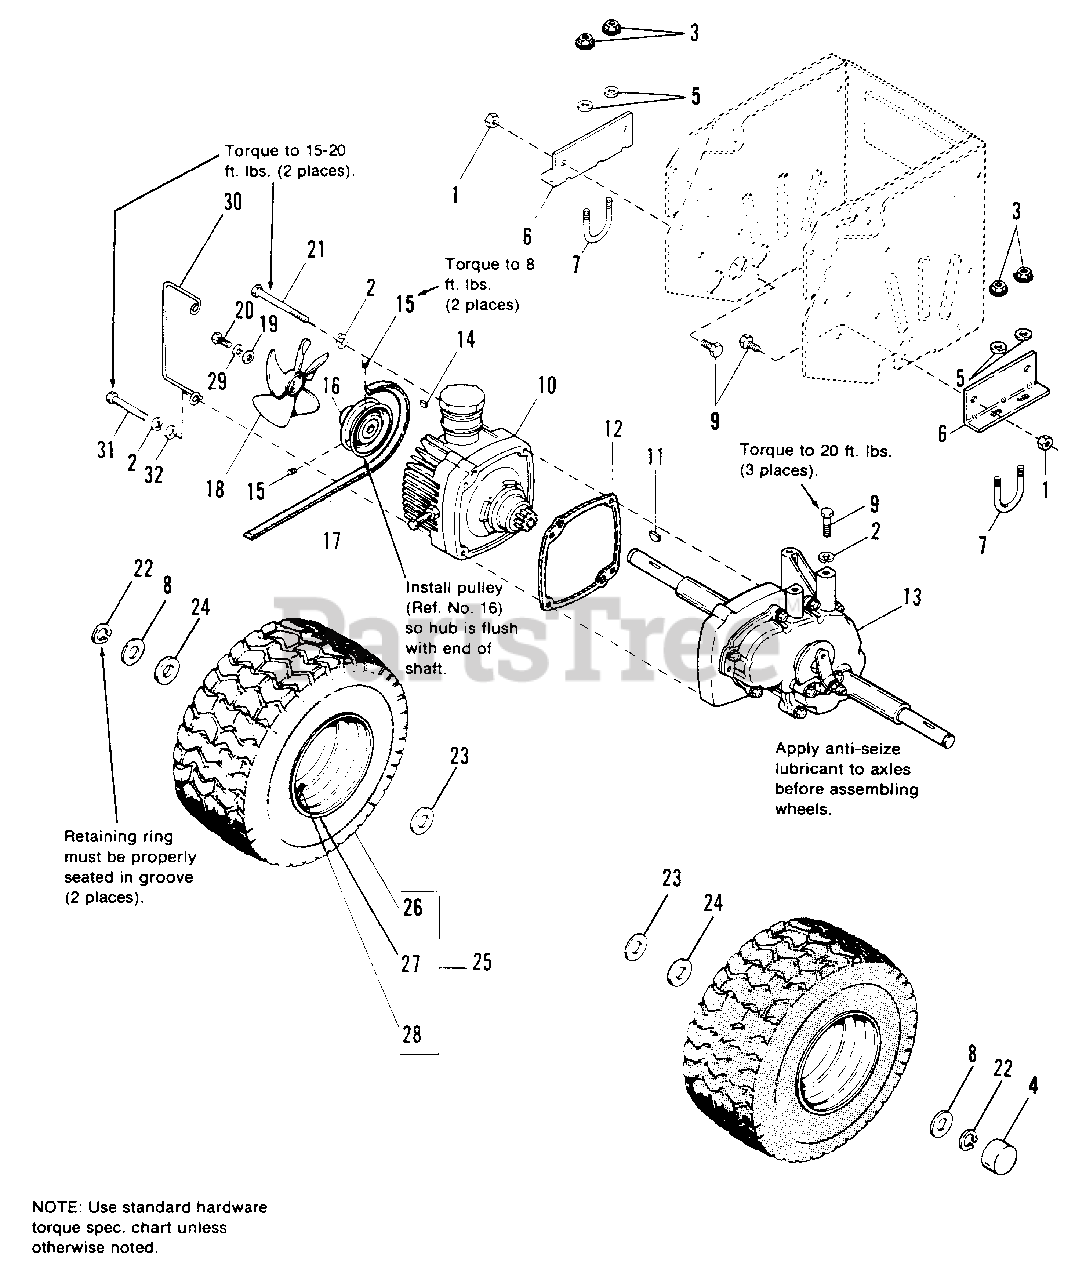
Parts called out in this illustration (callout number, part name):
1	NUT, Hex, 3/8-16
2	LOCKWASHER, 3/8
3	NUT, Hex, Flange Lock, 5/16-18
4	CAP, Hub, Threaded
5	WASHER, 5/16
6	SUPPORT, Transmission
7	"U" BOLT, Axle
9	CAPSCREW, Hex, 3/8-16 x 1
10	TRANSMISSION, Hydrostatic (See following 2 pages for service parts)
11	KEY, Woodruff, #18, 1/4 x 1-1/4
13	GEAR REDUCTION & DIFFERENTIAL ASSY. (See pages 48-51 for parts list.)
14	KEY, Woodruff, #3, 1/8 x 1/2
15	SETSCREW, Socket Hd., Cup Pt., 1/4-28 x 1/2
16	PULLEY, Transmission
17	BELT, "V" Drive
18	FAN, 7" Diameter
19	WASHER, 1/4 x 1-1/4 x 14 Ga.
20	CAPSCREW, Hex, 1/4-2 x 1/2
21	CAPSCREW, Hex, 3/8-16 x 3
22	RING, Retainer
24	WASHER, Plain, 1-1/32 x 1-3/4 x 3/16
25	WHEEL & TIRE ASSY. 18 x 8.50-8
26	TIRE, 18 x 8.50-8 (Carlisle), Turf Mate
27	WHEEL ASSY.
28	VALVE STEM & CAP
29	LOCKWASHER, 1/4
30	STOP, Drive Belt
31	CAPSCREW, Hex, 3/8-16 x 3-1/4, Gr. 5
32	WASHER, 3/8, Std.
